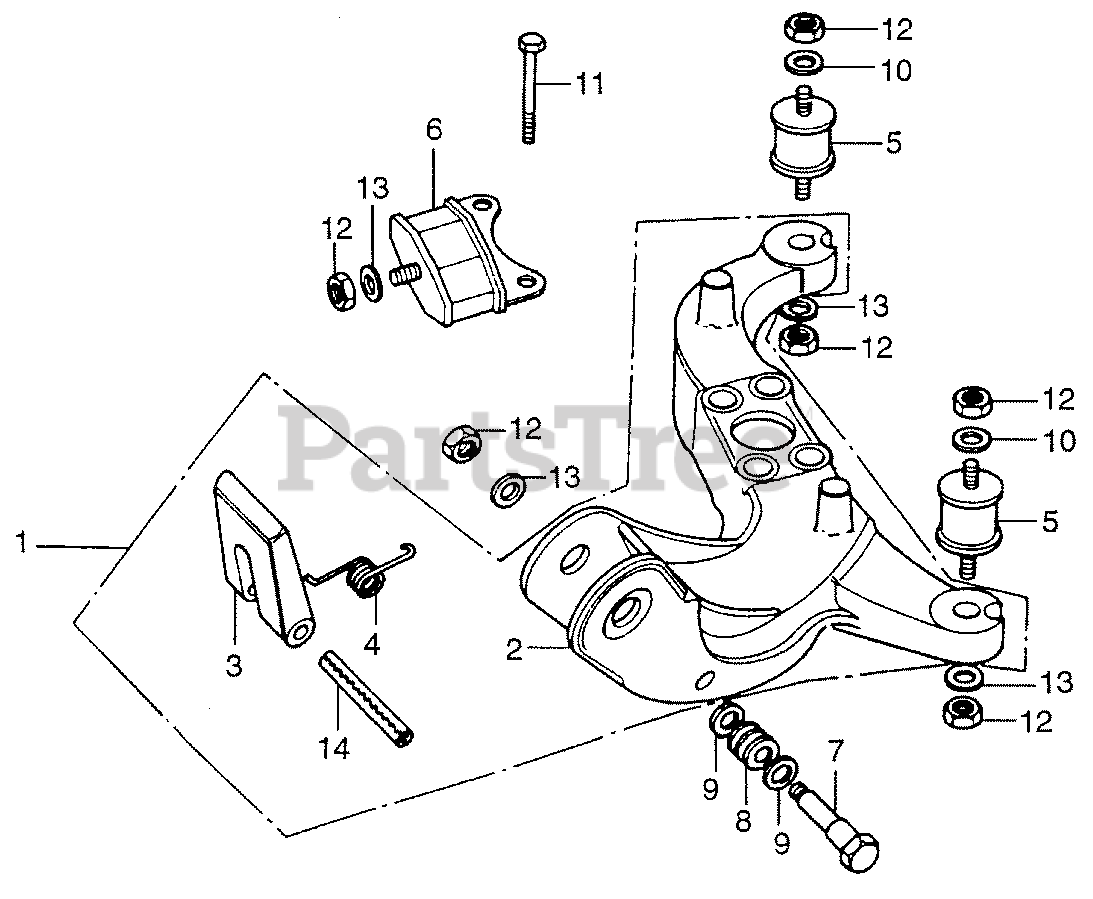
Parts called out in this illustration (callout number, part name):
1	FRAME, SETTING *PB1* (DARK BLUE)
2	FRAME, SETTING *PB1* (DARK BLUE) (NOT AVAILABLE)
3	STOPPER, HANDLE *PB1* (DARK BLUE)
4	SPRING, HANDLE
5	RUBBER, SETTING (UPPER) (NOT AVAILABLE)
6	RUBBER, THRUST SETTING (NOT AVAILABLE)
7	SCREW, HANDLE PIVOT
8	SPRING, HANDLE PIVOT
9	WASHER, PLAIN (10MM)
10	WASHER (8MM)
11	BOLT, HEX. (6X40)
12	NUT, HEX. (8MM)
13	WASHER, PLAIN (8MM)
14	PIN, SPRING (6X50)
